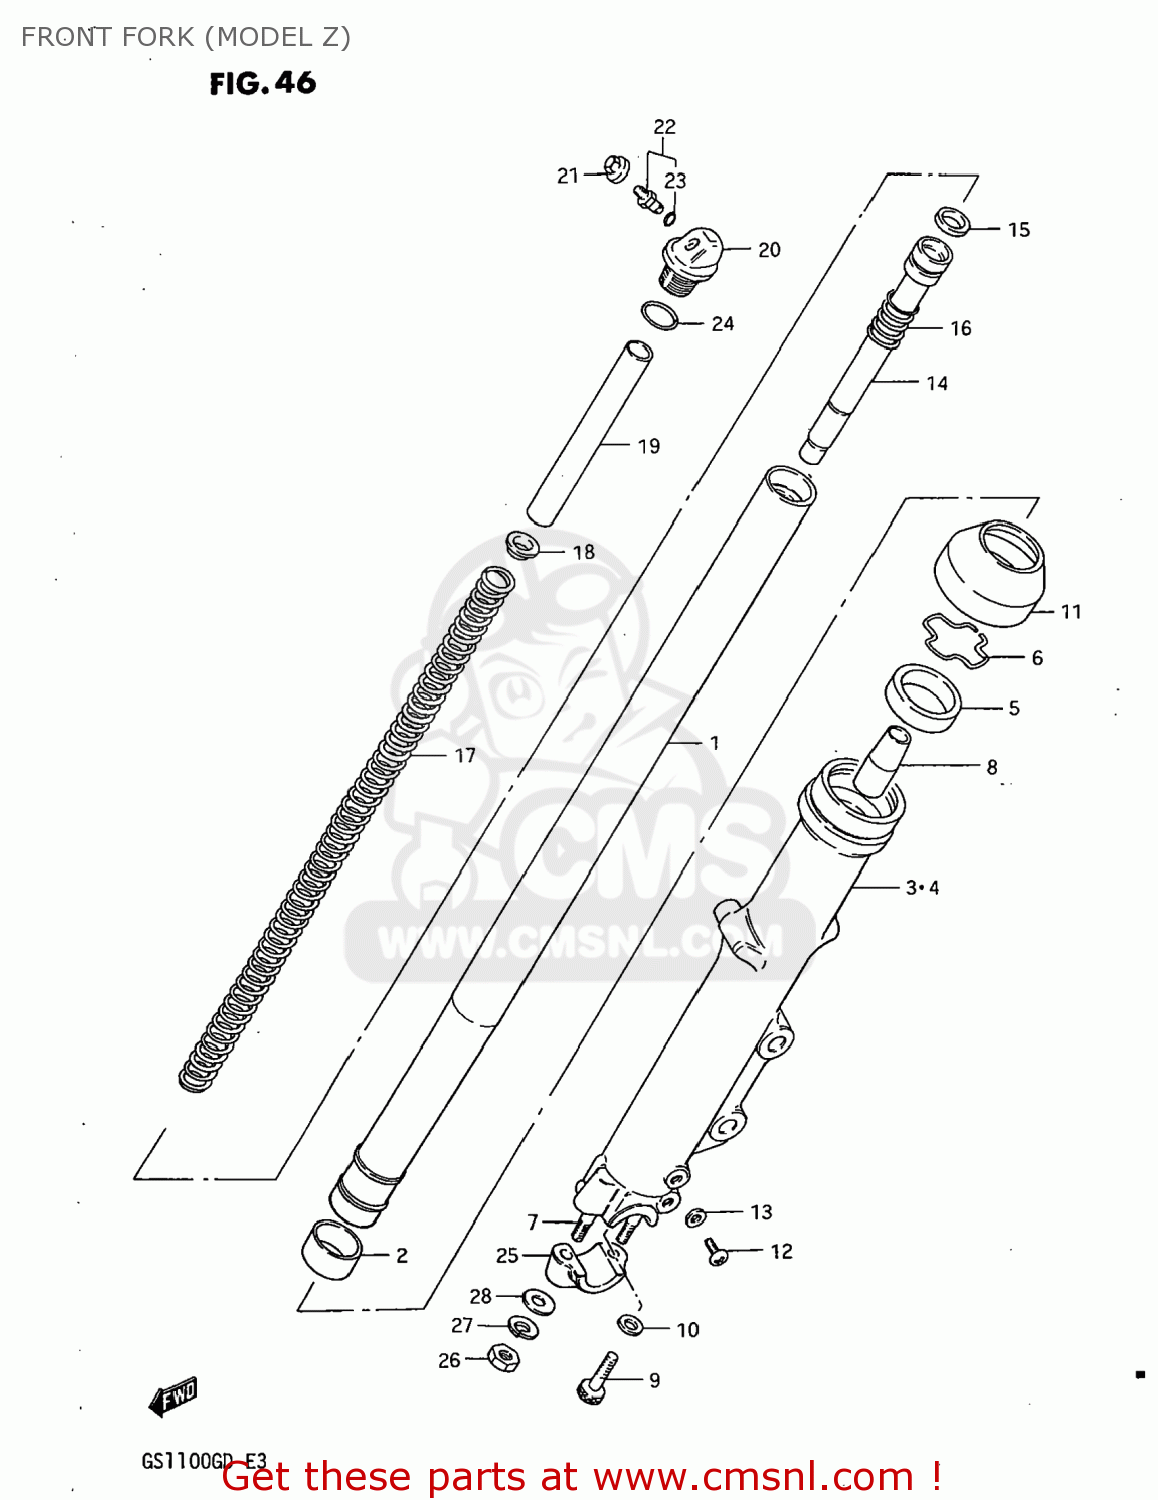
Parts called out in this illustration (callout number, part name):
1	TUBE,FORK,INNER
2	PISTON
3	TUBE,FORK,OUTER,RIGHT
4	TUBE,FORK,LEFT,OUTER
5	OIL SEAL,FRONT FORK
6	RING,STOPPER
7	STUD
8	PIECE,OIL LOCK
9	BOLT,FORK CYLINDER(10X25)
10	GASKET (NAS)
11	SEAL,DUST
12	SCREW
13	GASKET,DRAIN,PLUG (NAS)
14	CYLINDER,FRONT FORK
15	RING,PISTON
16	SPRING,REBOUND
17	SPRING,FRONT FORK
18	GUIDE,FRONT FORK SPRING C
19	SPACER,SPRING
20	CAP,FORK INNER TUBE
21	CAP,VALVE
22	VALVE
23	O RING
24	O RING
25	HOLDER,AXLE
26	NUT (8MM)
27	LOCK WASHER
28	WASHER
